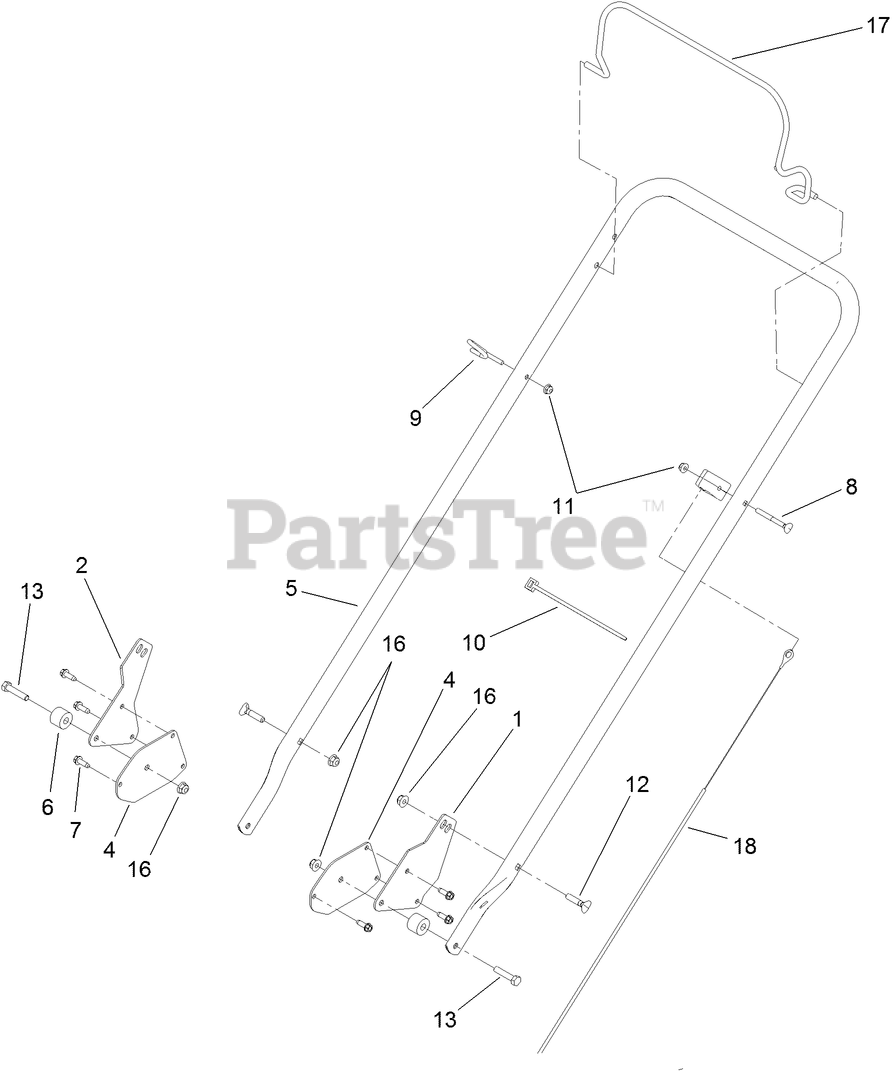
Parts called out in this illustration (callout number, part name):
1	SUPPORT-STRUT, LH
2	SUPPORT-STRUT, RH
4	PLATE-HANDLE
7	SCREW-HWHTF
8	SCREW-HANDLE
9	GUIDE-ROPE
10	TIE-CABLE
11	NUT-HF
12	SCREW-HANDLE
13	SCREW-HH
16	NUT-HF, NI
17	BAIL-BRAKE
18	CABLE-BRAKE
